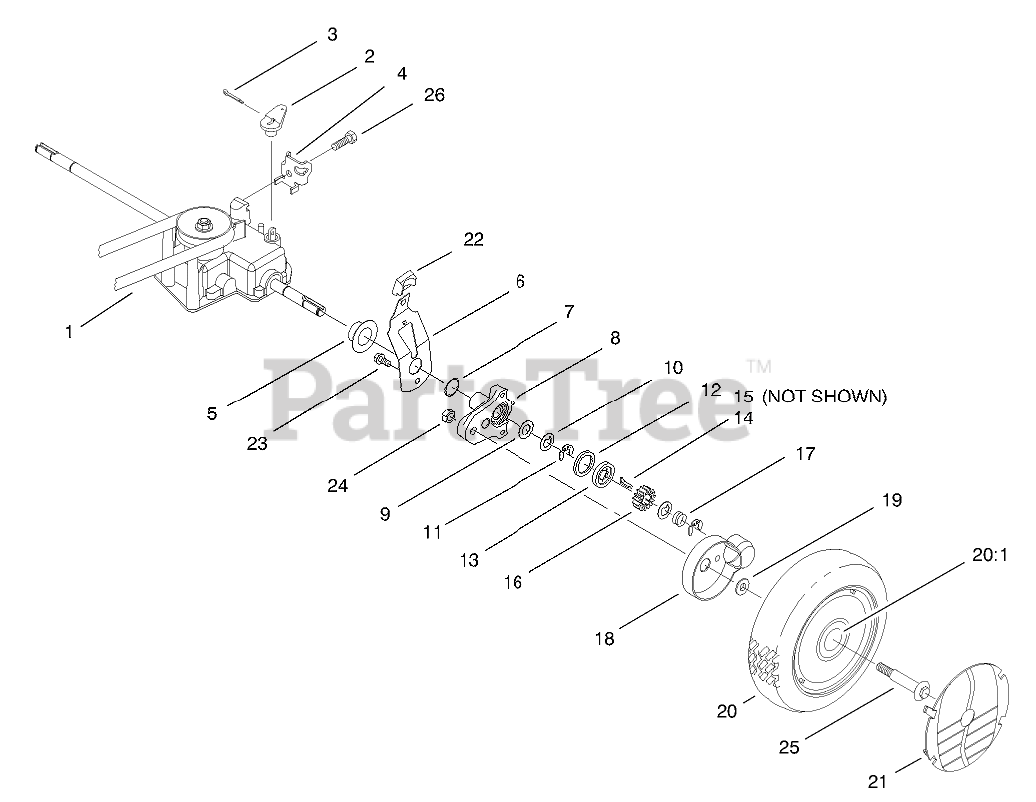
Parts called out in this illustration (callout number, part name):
1	V-BELT E
2	LEVER-SHIFT
3	PIN-COTTER
4	CLAMP-CABLE
5	CAP-END
6	SPRING ARM ASM
7	O-RING
8	PIVOT ARM ASM
9	WASHER-ARM, PIVOT
10	WASHER-THRUST, KEYED
11	RING-CLIP, LOCKING
12	RING-FRICTION
13	WASHER-CLUTCH
14	KEY-ROCKING, LH
15	KEY-ROCKING, RH
16	GEAR-PINION
17	SPRING-COMPRESSION
18	COVER-WHEEL
19	SPACER-COVER, WHEEL
20	Wheel-ASM
20:1	BUSHING
21	COVER-WHEEL
22	KNOB-ARM
23	SCREW-HWH
24	NUT-LOCK
25	BOLT-WHEEL
26	SCREW-HWHTF
